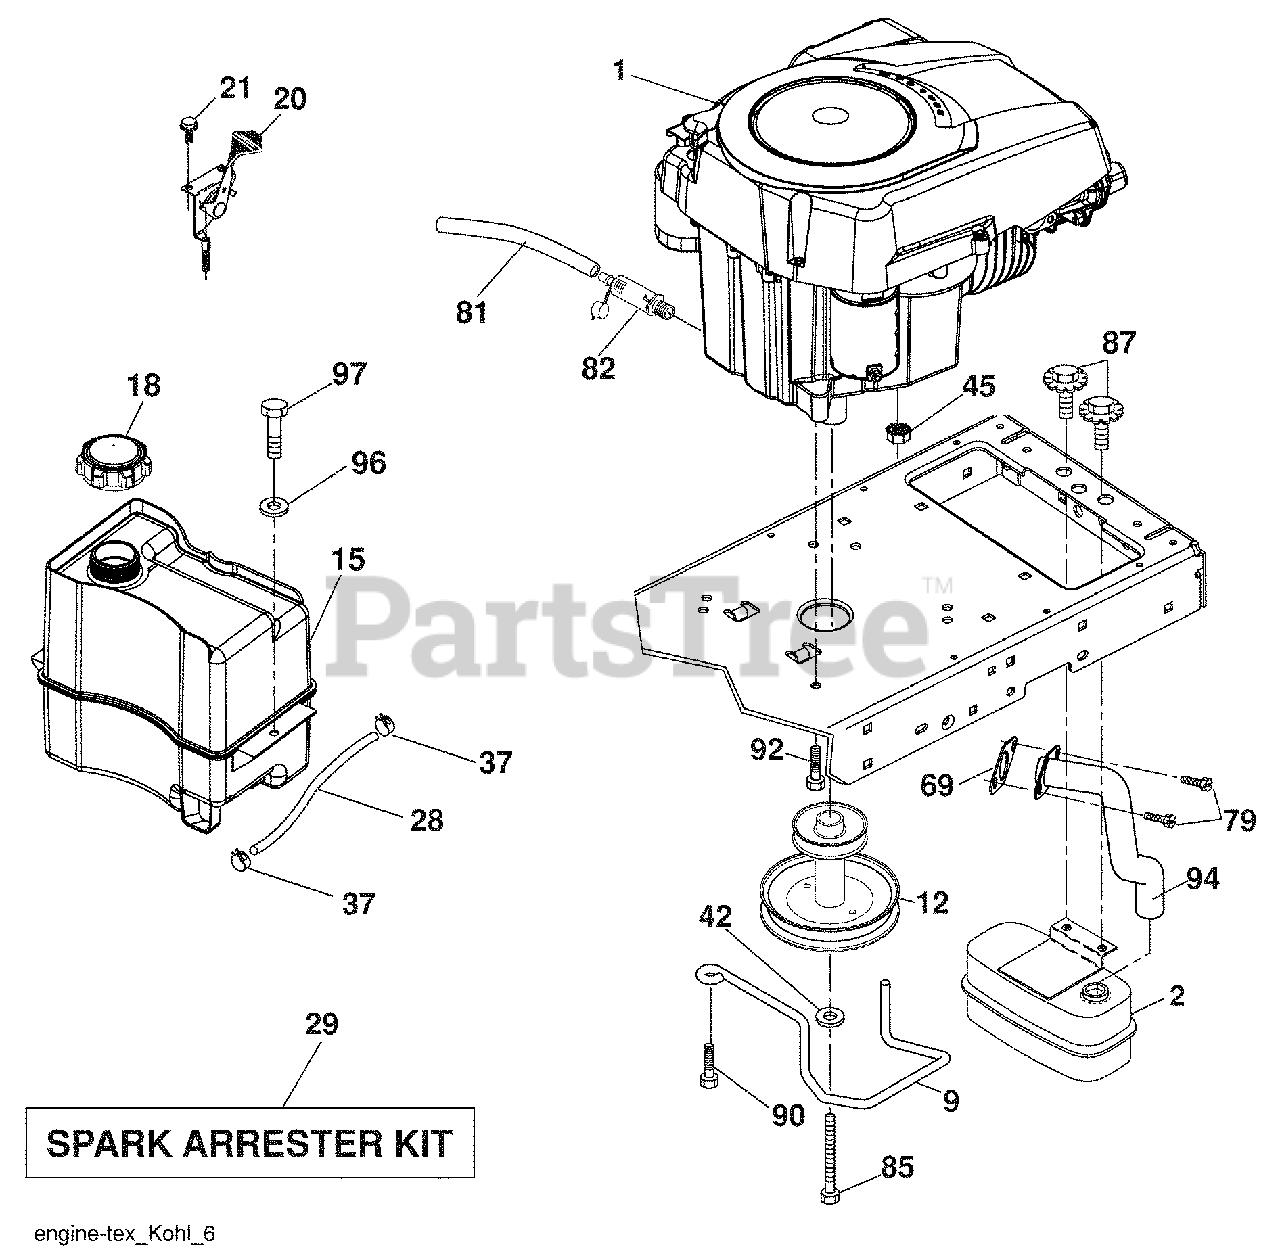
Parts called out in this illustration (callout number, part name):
9	Keeper Belt Engine
12	Pulley Engine
15	Tank Fuel
18	Cap Asm
20	Control Throttle
21	Screw #10 x 0.750
28	Fuel Line
29	Spark Arrester Kit
37	Clamp Hose
42	Washer Lock 7/16
45	Nut Keps Hex 1/4-20 unc
79	Screw Socket Hd. 5/16-18 x .75
81	Tube Drain Oil Easy
82	Plug Drain Oil
85	Bolt Hex 7/16-20 x 4 x Gr. 5-1.5 Thr
87	Bolt 5/16-18 unc x 3/4 w/Sems
90	Screw 3/8-16 x 1
92	Screw 3/8-16 x 1
94	Tube Exhaust
96	Washer 9/32 x 7/8 x 16 Ga.
97	Screw 1/4-20 x 3/4
